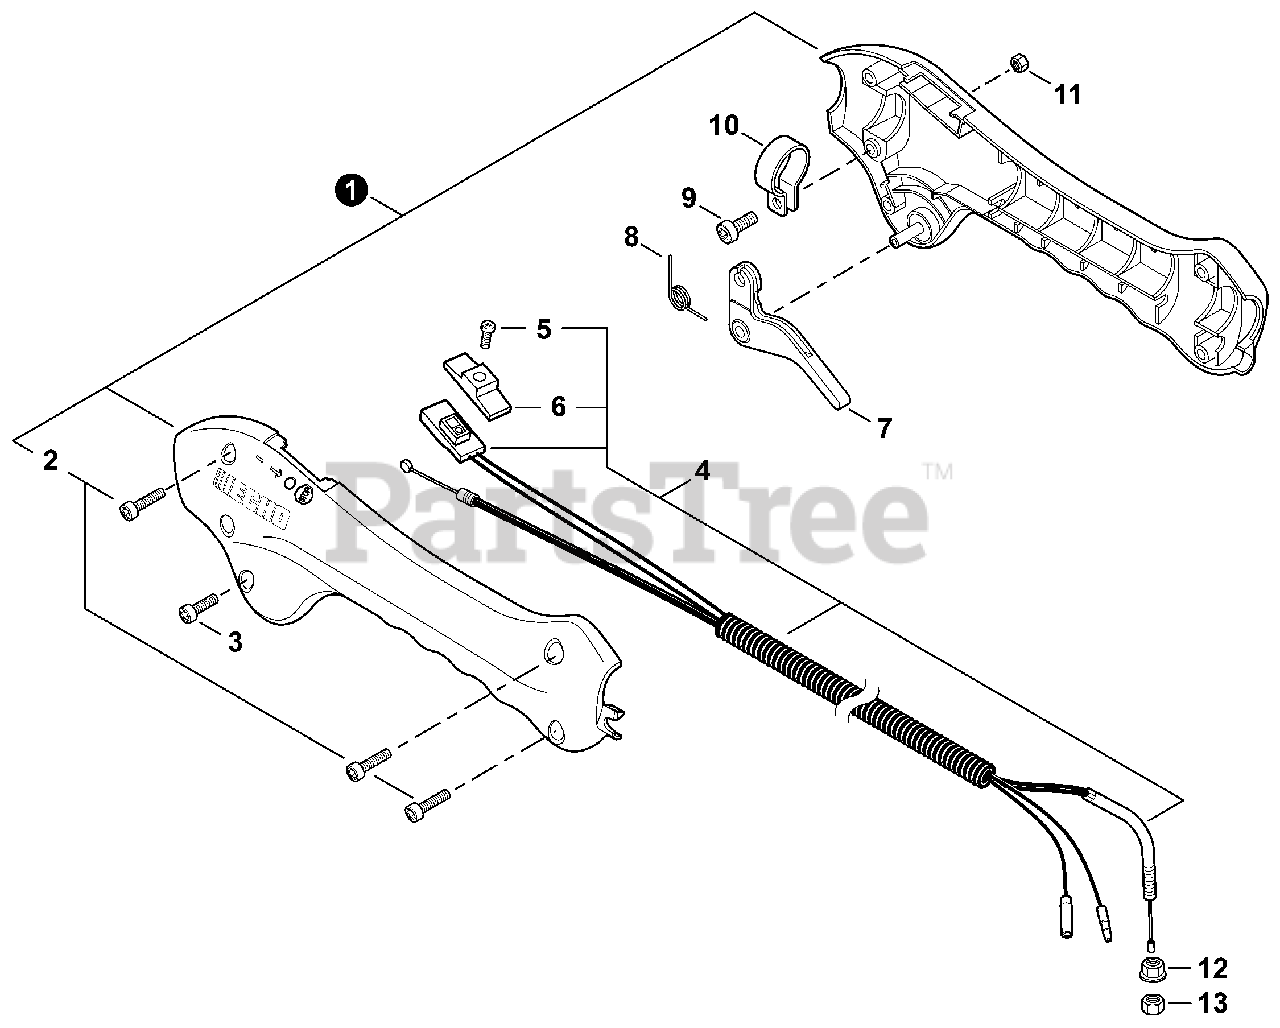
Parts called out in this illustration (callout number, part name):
1	CONTROL HANDLE KIT
2	BOLT, TORX 4x16
3	BOLT, TORX 4x12
4	CABLE ASSY, CONTROL
5	SCREW 3x10
6	KNOB, SWITCH - ORANGE
7	TRIGGER, THROTTLE
8	SPRING, TORSION
9	BOLT, TORX 5x12
12	NUT, FLANGE M6
